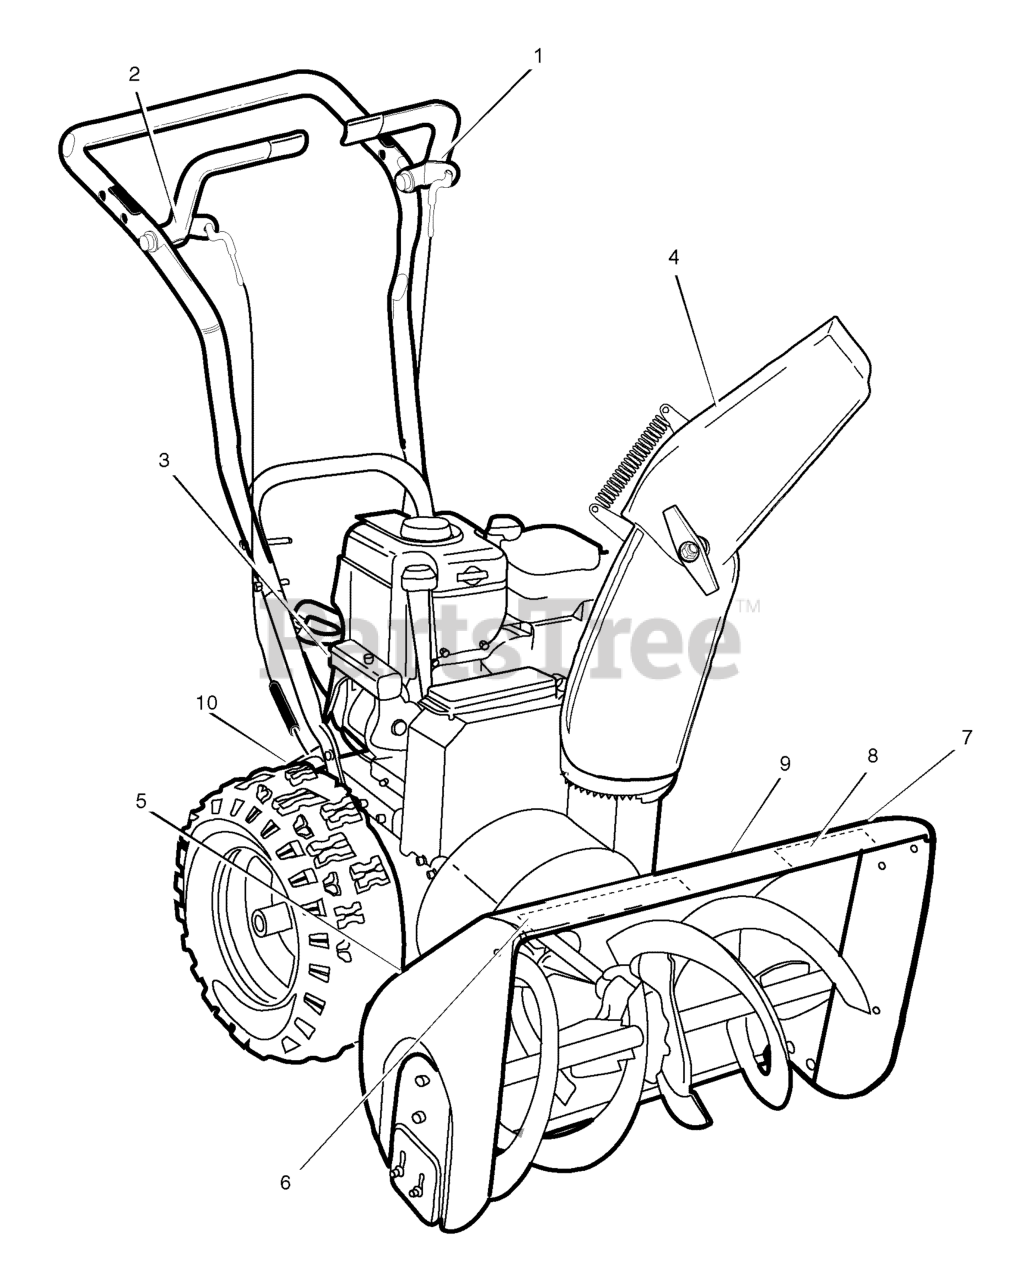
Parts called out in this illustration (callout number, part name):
1	DECAL, DRIVE SYMBOL
2	DECAL, AUGER SYMBOL
3	DECAL, GEAR SELECT
4	DECAL, ISO CHUTE
5	DECAL, ISO AUGER
6	DECAL, CANADIANA
7	DECAL, FACE HEAD PHONES
8	DECAL, 800/61 TOP AUGER WHITE
9	DECAL, 104db CE
10	DECAL, ID PLATE
